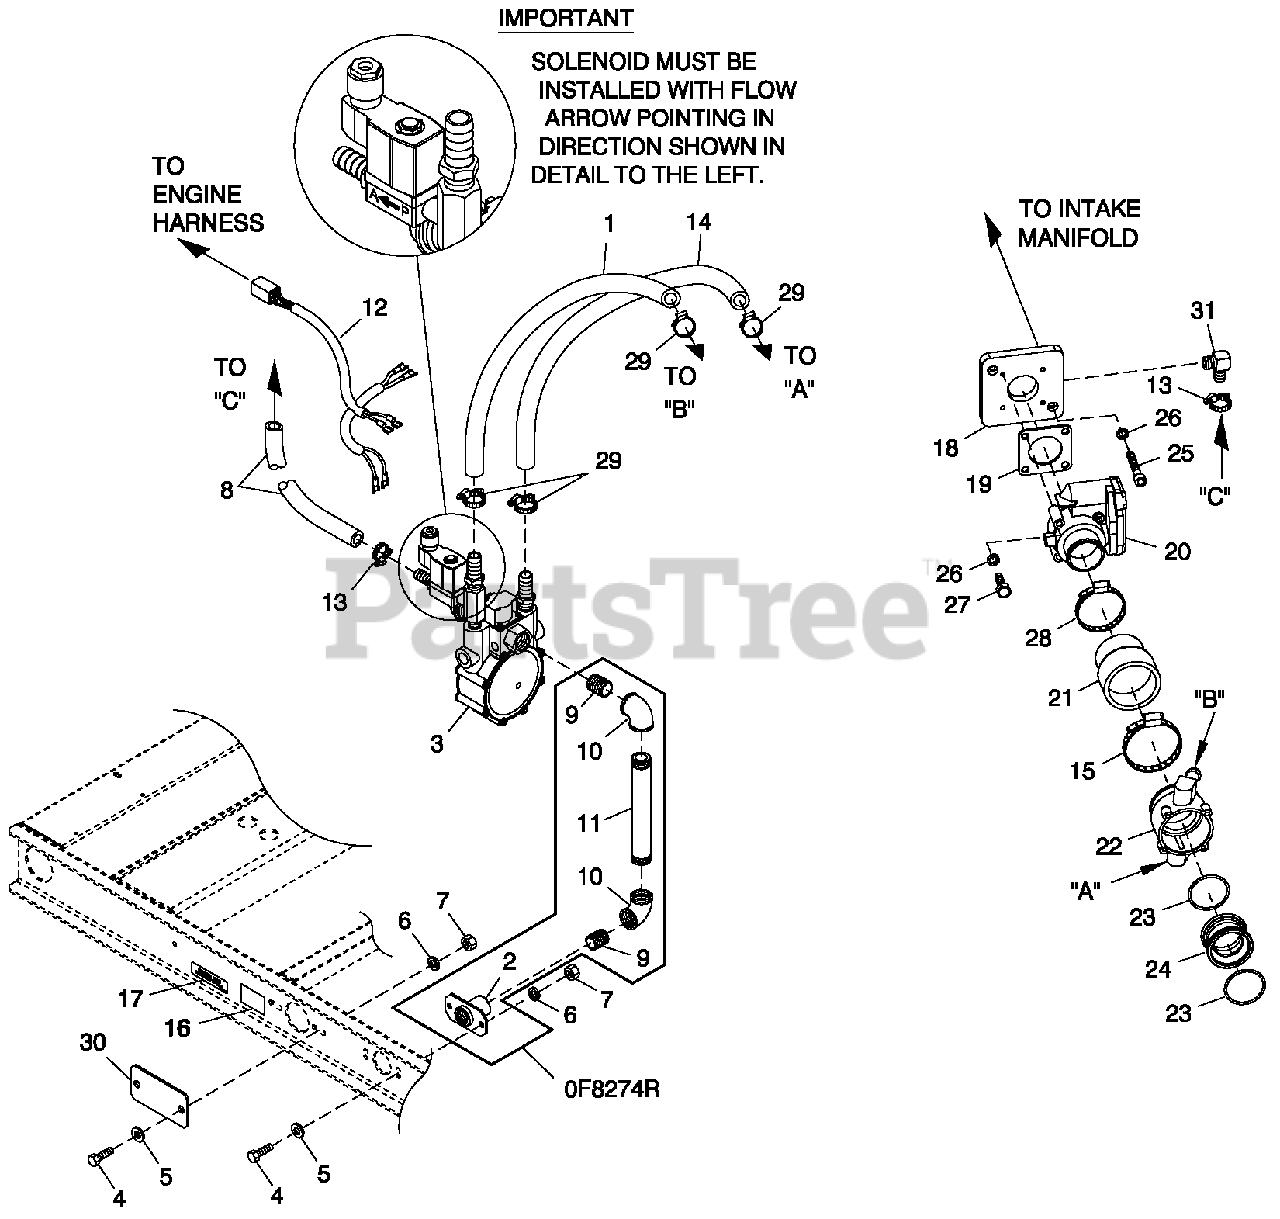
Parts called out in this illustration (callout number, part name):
1	HOSE 3/4 ID SAE-30R2 (28" LG)
2	FLANGE FUEL INLET
3	ASSYREGULATR60KWLP
4	SCREW HHC $8-1.25X20 G8.8
5	WASHER FLAT 5/16 ZINC
6	WASHERLOCK M8-5/16
7	NUT HEX M8-1.25 G8 CLEAR ZINC
8	HOSE 3/8 ID SINGLE BRAID (17" LG)
9	NIPPLE CLOSE 3/4X1.375
10	ELBOW 90D 3/4 NPT
11	NIPPLE PIPE 3/4 NPT X 7
12	HARNESS FUEL JUMPER SINGLE REG
13	CLAMP HOSE #8 .53-1.00
14	HOSE 3/4 ID SAE-30R2 (22" LG)
15	CLAMP HOSE #44 2.31-3.25
16	DECAL INLET PRESSURE
17	DECAL FUEL INLET LPG
18	INTAKE ADAPTER BOSCH
19	GASKET BOSCH 32
20	ACTUATOR BOSCH 40 GOVERNOR
21	REDUCER RUBBER 3.0"-2.00"
22	MIXER 40/60MM ACTUATOR ASSY
23	O-RING 2-3/4X3/32X2-15/16
24	VENTURI THROTTLE 32MM
25	SCREW SHC M6-1.0 X 25 G12.9 ZP
26	WASHER LOCK M6-1/4
27	SCREW HHC M6-1.0X 50 G8.8
28	CLAMP HOSE #36 1.88-2.75
29	CLAMP HOSE #10 .56-1.06
30	COVER FUEL INLET NG
31	BARBED EL 901/4 NPT X 3/8
